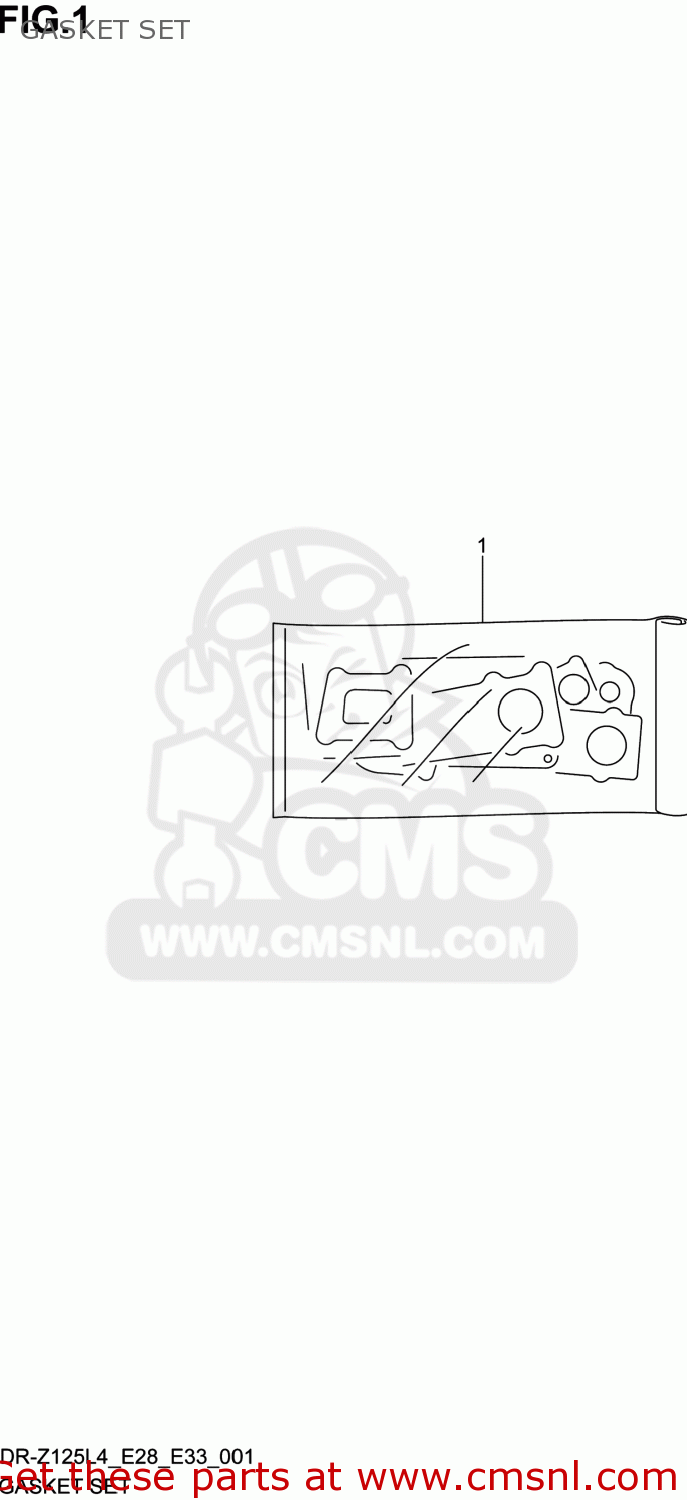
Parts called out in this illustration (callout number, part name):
1	GASKET SET (NAS)
2	GASKET.CYLINDER HEAD (NAS)
3	GASKET,CYLINDER (NAS)
4	GASKET,CLUTCH COVER (NAS)
5	GASKET,MAGNETO COVER (NAS)
6	GASKET,TENSIONER ADJUSTER (NAS)
7	GASKET (NAS)
8	CONNECTOR,MUFFLER
9	GASKET(8.5X17X2.3) (NAS)
10	GASKET(13.8X18.8X4.8) (NAS)
11	O RING(D:1.9,ID:8.6)
12	O RING(D:1.9,ID:13)
13	O RING(D:3.1,ID:16.8)
14	O RING(D:2.4,ID:21.8)
15	O RING(D:3.1,ID:22.7)
16	O RING(D:3,ID:29.5)
17	O RING(D:2.4,ID:52.6)
18	O RING(D:2.4,ID:60.5)
